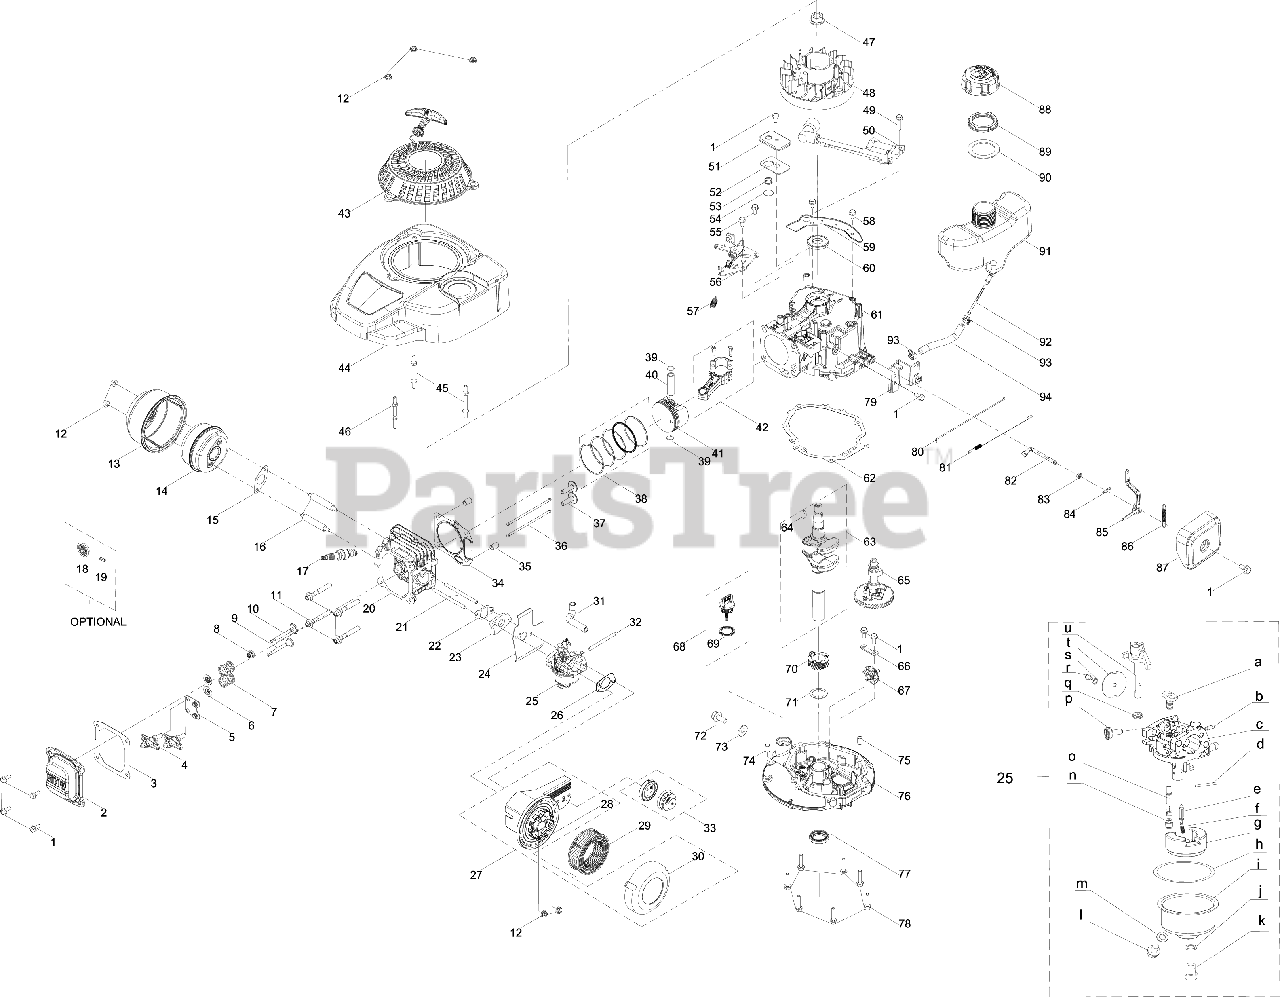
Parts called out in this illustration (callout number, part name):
1	BOLT M6-1 x 14 GR8.8
2	VALVE COVER
3	VALVE COVER GASKET
4	ROCKER ARM ASSEMBLY
5	PUSH ROD GUIDE
6	VALVE SPRING RETAINER
7	VALVE SPRING
8	INTAKE VALVE SEAL
9	EXHAUST VALVE
10	INTAKE VALVE
11	SCREW M8 x 54 GR10
13	MUFFLER SHIELD
14	MUFFLER ASSEMBLY
15	MUFFLER GASKET
16	STUD M6-1 x 76
17	SPARK PLUG
18	SPARK ARRESTOR
19	SCREW M3.5 x 9.5
20	CYLINDER HEAD
21	STUD M6 x 98
22	CARBURETOR INSULATOR GASKET
23	CARBURETOR INSULATOR
24	CARBURETOR GASKET
25	CARBURETOR ASSEMBLY
26	AIR FILTER BASE GASKET
27	AIR FILTER ASSEMBLY
28	AIR FILTER BASE
29	PAPER AIR FILTER
30	AIR FILTER COVER
31	BREATHER HOSE
32	PRIMER HOSE
33	VENTED PRIMER ASSEMBLY
34	CYLINDER HEAD GASKET
37	TAPPET (LIFTER)
38	PISTON RING SET
39	SNAP RING-PISTON PIN
40	PISTON PIN
41	PISTON
42	CONNECTING ROD ASSEMBLY
43	STARTER RECOIL ASSEMBLY
44	ENGINE SHROUD ASSEMBLY
45	STUD M6 x 75
46	STUD M6 x 73
47	FLYWHEEL NUT
48	FLYWHEEL
49	BOLT M6-1 x 25 GR8.8
50	IGNITION COIL ASSEMBLY
51	BREATHER COVER PLATE
52	BREATHER COVER GASKET
53	BREATHER VALVE SPRING
54	BREATHER VALVE
55	BOLT M6-1 x 12 GR8.8
56	ENGINE BRAKE ASSEMBLY
57	BRAKE SPRING
58	BOLT M6-1 x 10 GR8.8
59	SHROUD COVER PLATE
60	UPPER CRANKSHAFT SEAL
62	CRANKCASE COVER GASKET
63	CRANKSHAFT
64	FLYWHEEL KEY
65	CAMSHAFT ASSEMBLY
66	GOVERNOR GEAR MOUNTING PLATE
67	GOVERNOR GEAR/SHAFT ASSEMBLY
68	DIPSTICK ASSEMBLY
69	DIPSTICK O-RING
70	CRANKSHAFT TIMING GEAR
71	THRUST WASHER
72	OIL DRAIN PLUG
73	WASHER
74	DOWEL PIN
75	DOWEL PIN
76	CRANKCASE COVER
77	LOWER CRANKSHAFT SEAL
78	BOLT-M6-1 x 28 GR8.8
79	COMPONENT BRACKET
80	THROTTLE LINKAGE
81	THROTTLE LINKAGE SPRING
82	GOVERNOR ARM SHAFT
83	GOVERNOR SEAL
84	COTTER PIN
85	GOVERNOR ARM ASSEMBLY
86	GOVERNOR SPRING
87	GOVERNOR SHIELD
88	FUEL CAP ASSEMBLY
89	FUEL TANK NUT
90	FUEL TANK UPPER GROMMET
92	FUEL FILTER
93	HOSE CLAMP
94	FUEL HOSE
